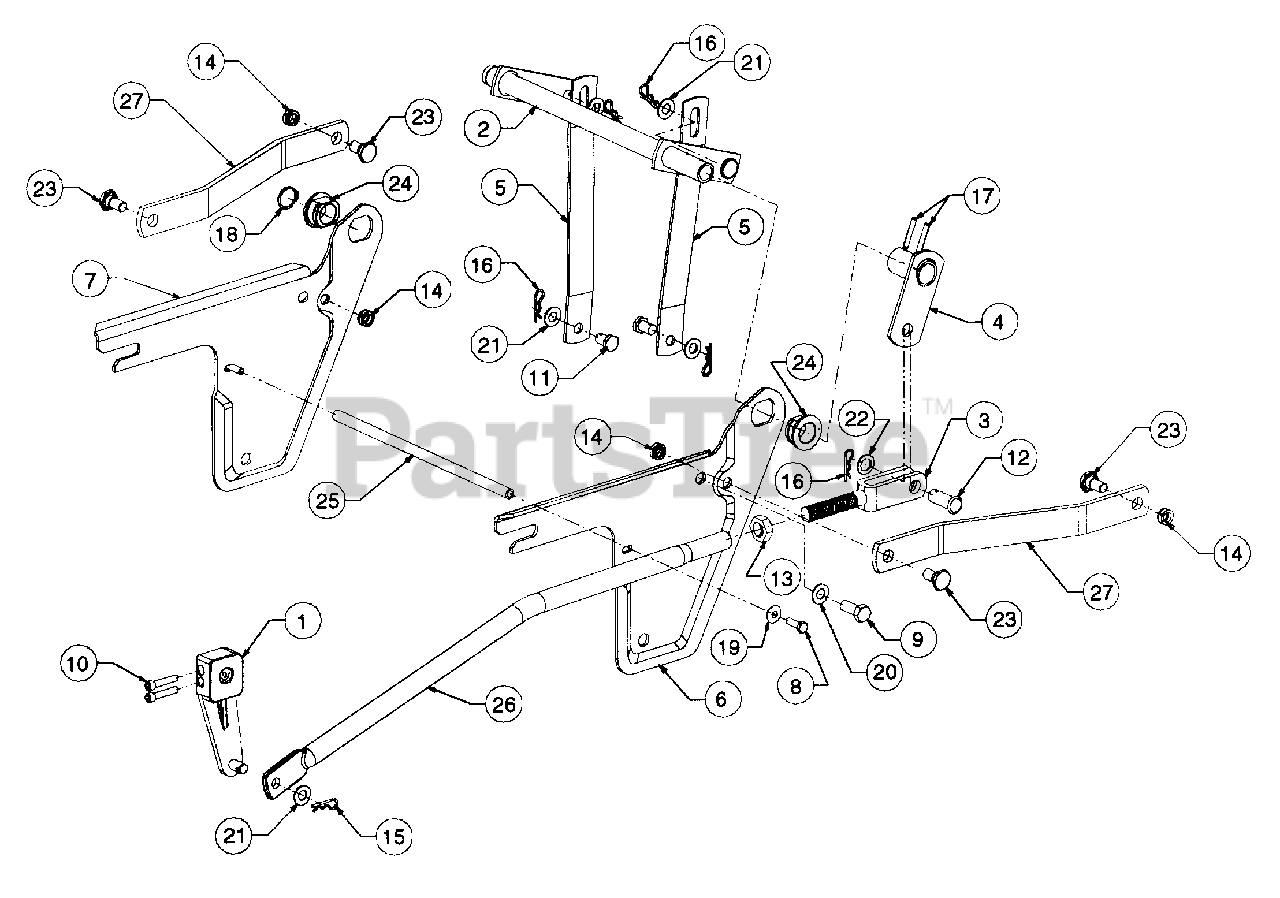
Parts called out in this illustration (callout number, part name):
1	Bracket Ass'y, Hydro Lift
9	Screw, Hex Cap, 1/2-13 X 1.25 GR5
10	Screw, Socket Hd
11	Pin, Lift Bracket
12	Pin, Clevis
13	Nut, Hex Jam, 3/4-10
14	Nut, Hex Insert Lock Jam, 1/2-20
15	Pin, Internal Cotter
16	Pin, Internal Cotter
17	Pin, Spiral Spring, .25 Dia X 1.5 Lg
18	Ring, Snap
19	Washer, Bell, .345 X .88 X .06
20	Washer, Bell
21	Washer, Flat, .510 X 1.0 X .06
22	Washer, Flat, 5/8 X 1.0 X .063
23	Bolt, Shoulder, .62 Dia X .30 Lg
24	Bearing, Flange w/Flats
25	Rod, Carriage Bracket Support
